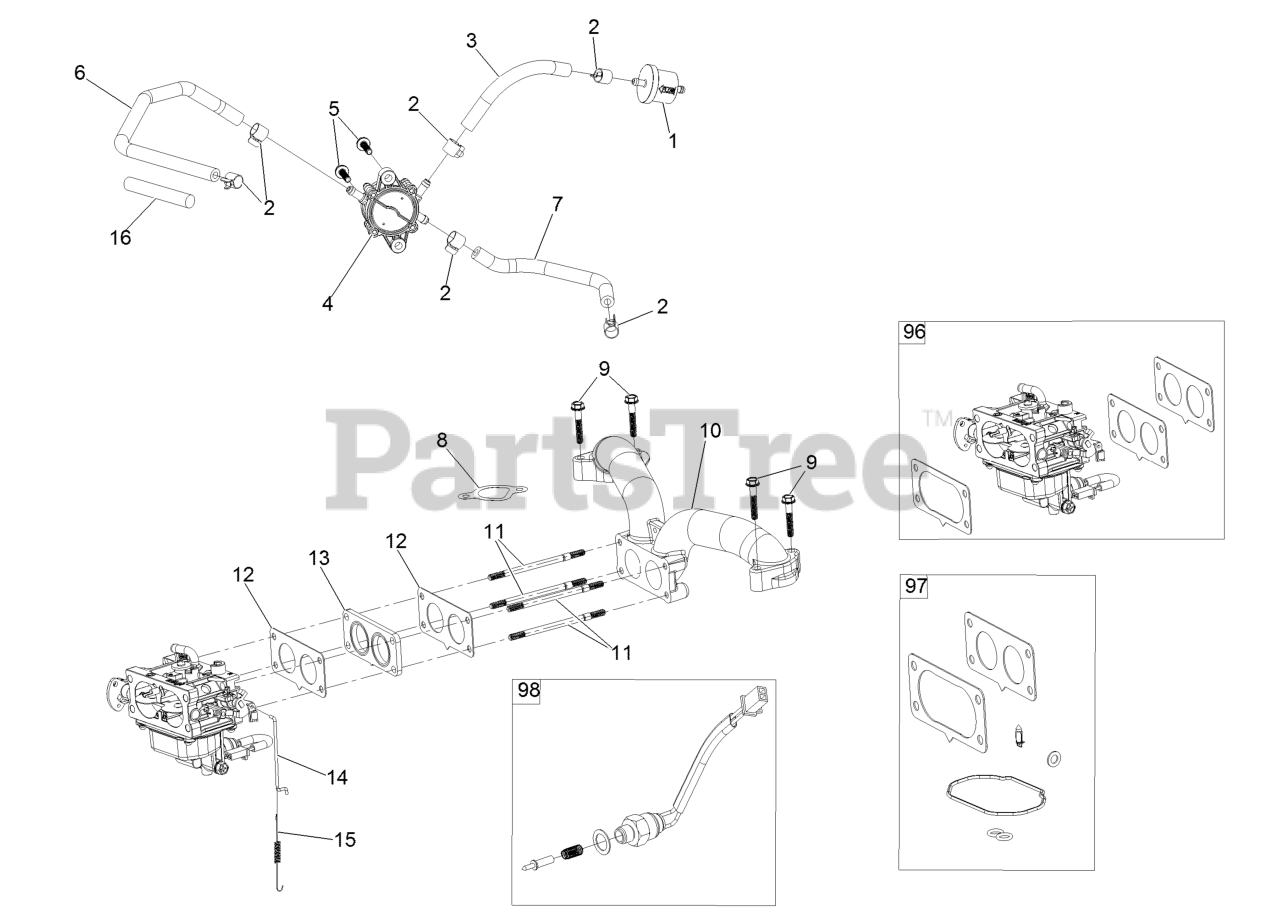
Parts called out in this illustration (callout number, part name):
1	Filter-Fuel
2	Clamp-Fuel Line
3	Line-Fuel
4	Pump-Fuel
5	Screw-HHF
6	Hose-Fuel
7	Hose-Fuel
8	Gasket-Intake
9	Screw-HHF
10	Manifold-Intake
12	Gasket-Carburetor
13	Insulator-Carburetor
14	Linkage-Throttle
15	Spring-Return, Throttle
16	Sleeve-Fuel Line Protector
96	Carburetor Replacement Kit
97	Carburetor Repair Kit
98	Solenoid Kit
99	High Altitude Kit
